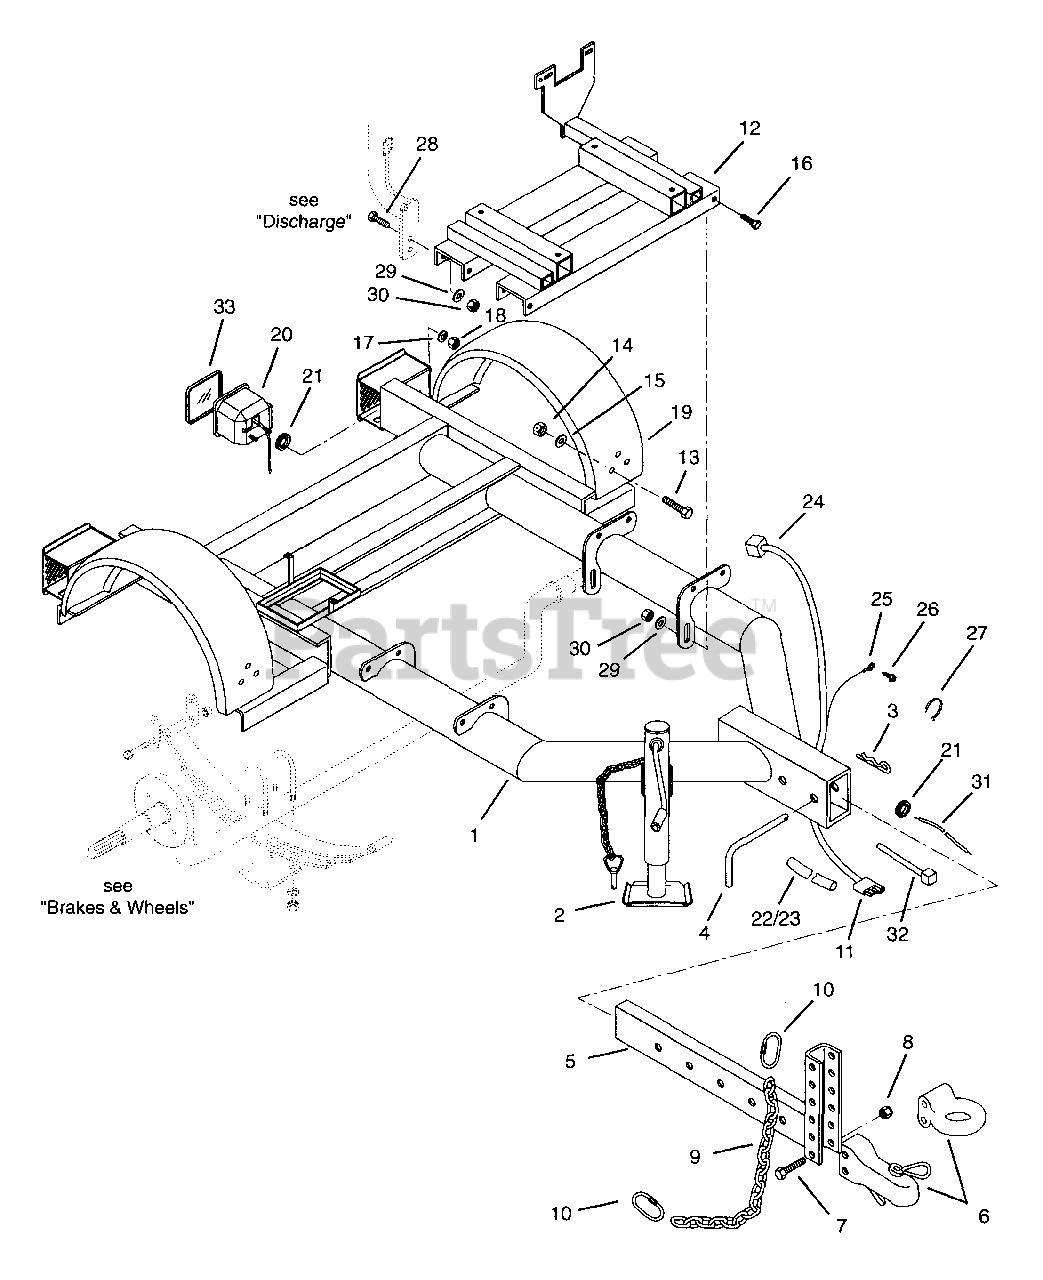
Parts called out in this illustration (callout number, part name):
1	Frame-Trailer Weldment
3	Pin-Hair-Internal .15 x 2.937
4	Pin-Hitch
6	Hitch-Ball 2 inch
6	Hitch-Ring
7	Bolt-Hex .62-11 x 4.25 Grade 5
8	Nut-Locking-Center .62-11
9	Chain-Safety - 4 ft long
10	Quick Link-Safety Type 5/16 inch
11	Harness-Wire
12	Cross brace-Engine
13	Bolt-Hex .31-18 x .75 Grade 5
14	Nut Locking-Center .31-18
15	Washer-Flat-Steel .38 x .875 x .083
16	Bolt-Hex .50-13 x 2.00 Grade 5
17	Washer-Locking-External .262 x .502 x .026
18	Nut-Locking-Center .25-20
19	Fender-Trailer
20	Light-Tail-Left Hand
20	Light-Tail-Right Hand
21	Grommet
22	Wire Covering
23	Electrical Tape
24	Connector
25	Ring Tongue Connector
26	Screw-Tapping-Hex Washer Head 8-32 x .50
27	Tie Wrap
28	Bolt-Hex .50-13 x 2.25 Grade 5
29	Washer-Flat-Steel .563 x 1.38 x .109
30	Nut-Locking-Center .50-13
31	Wire
32	Plug
33	Lens-Tail Light
